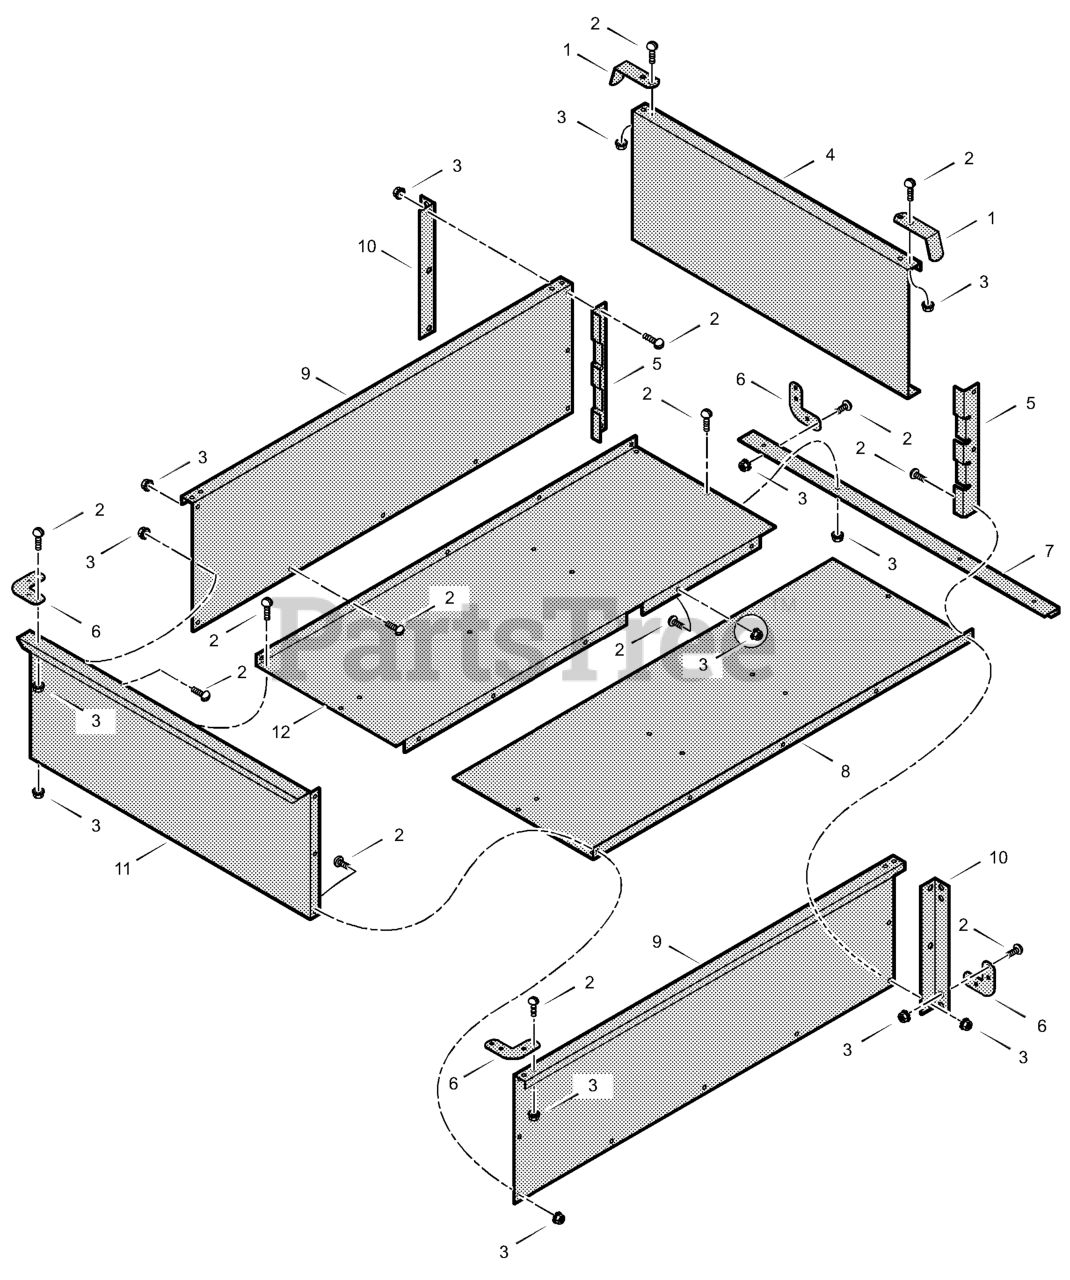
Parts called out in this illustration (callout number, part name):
1	Support, Side
2	Screw 1/4-20x0.50
3	Nut, Keps 1/4-20
4	Tailgate (Black)
5	Retainer, Tailgate
6	Bracket, Corner
7	Brace, Rear
8	Bottom, Right
9	Panel, Side (Black)
10	Support, Side
11	Panel, Front
12	Bottom, Left
